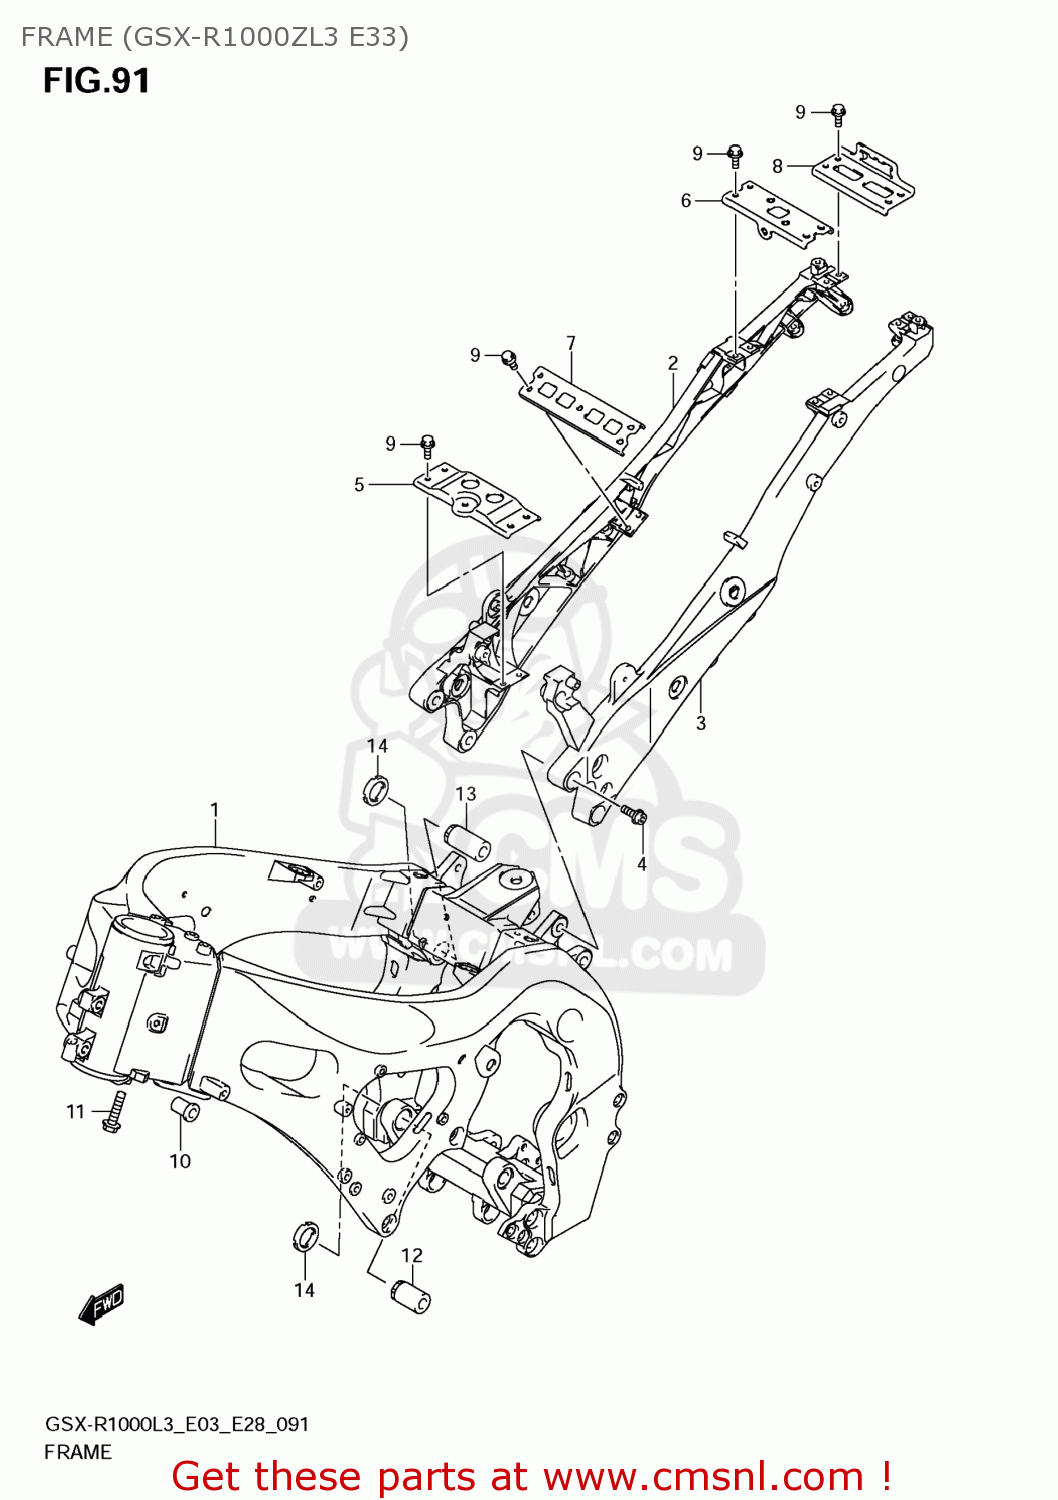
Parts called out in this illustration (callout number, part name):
1	FRAME(BLACK)
2	RAIL,SEAT,R
3	RAIL,SEAT,L
4	BOLT,SEAT RAIL
5	BRIDGE,SEAT RAIL FR
6	BRIDGE,SEAT RAIL UPR
7	BRIDGE,SEAT RAIL LWR
8	BRIDGE,SEAT RAIL RR
9	BOLT(6X12)
10	SPACER,ENGINE MOUNTING
11	BOLT(8X35)
12	BOLT,CRANK CASE ADJUST
13	BOLT,CRANK CASE ADJUST UPR
14	NUT,CRANK CASE ADJUST BOLT
